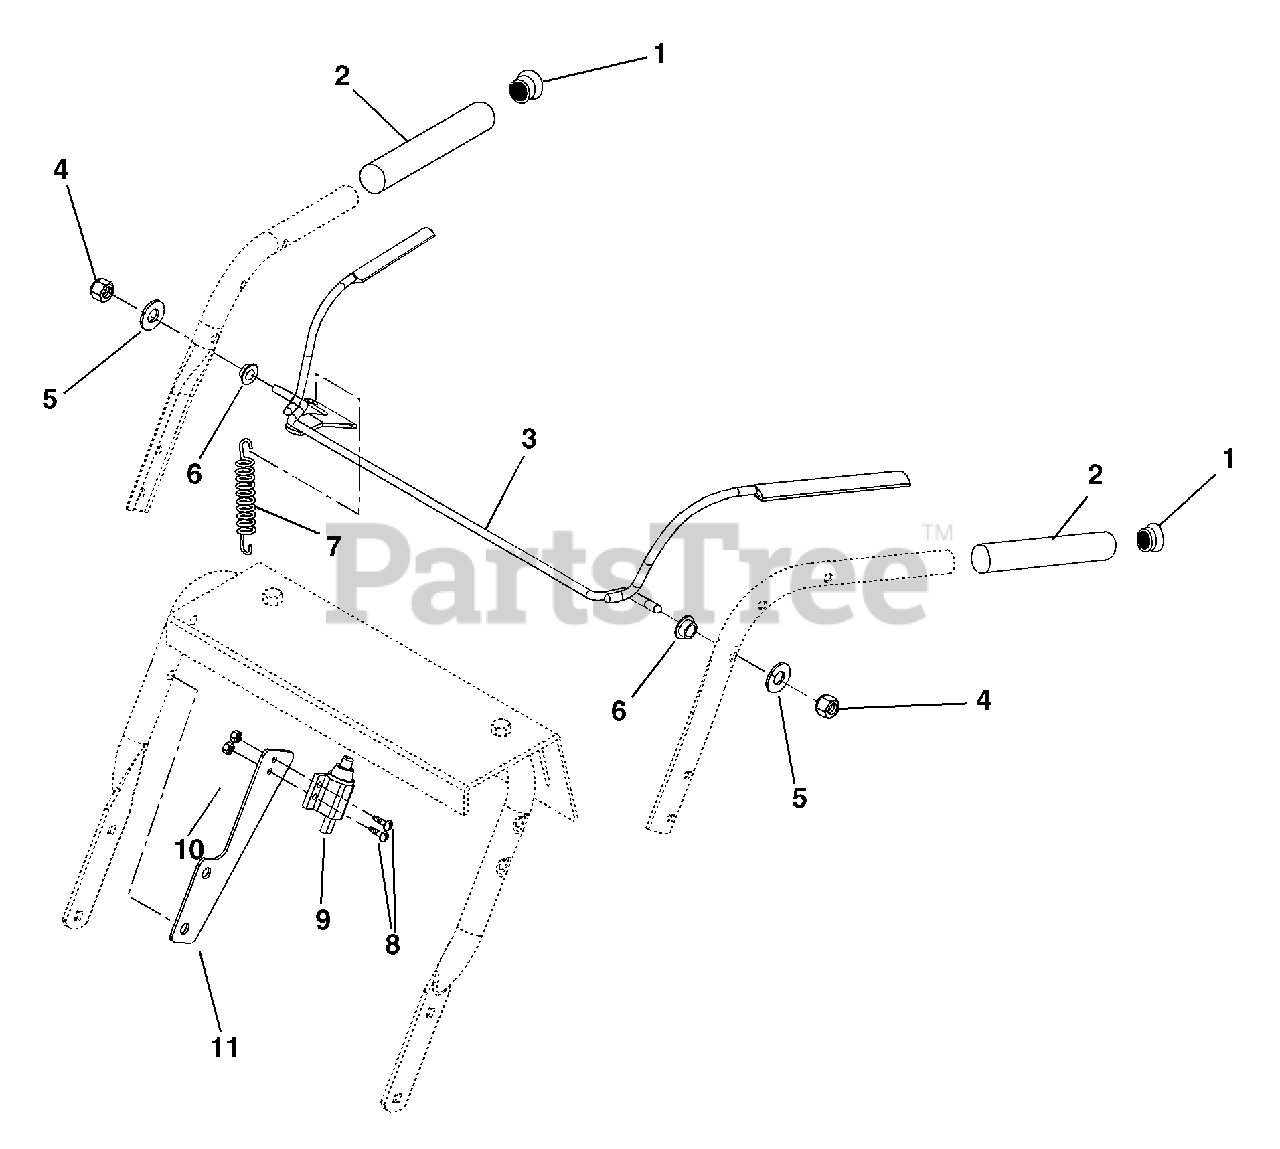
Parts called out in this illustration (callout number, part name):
1	Cap-Vinyl
2	Grip-Handle
3	Weldment, Rod
4	Nut-Locking-Center .31-18
5	Washer-Flat-Steel .344 x .688 x .065
6	Bushing-Flange
7	Spring-Tension .041 x .50 x 1.75
8	Screw-Machine 10-24 x .75
9	Switch-Single Pole N.O. with Cover
10	Nut-Locking-Nylon 10-24
11	Bracket-Switch Mounting
